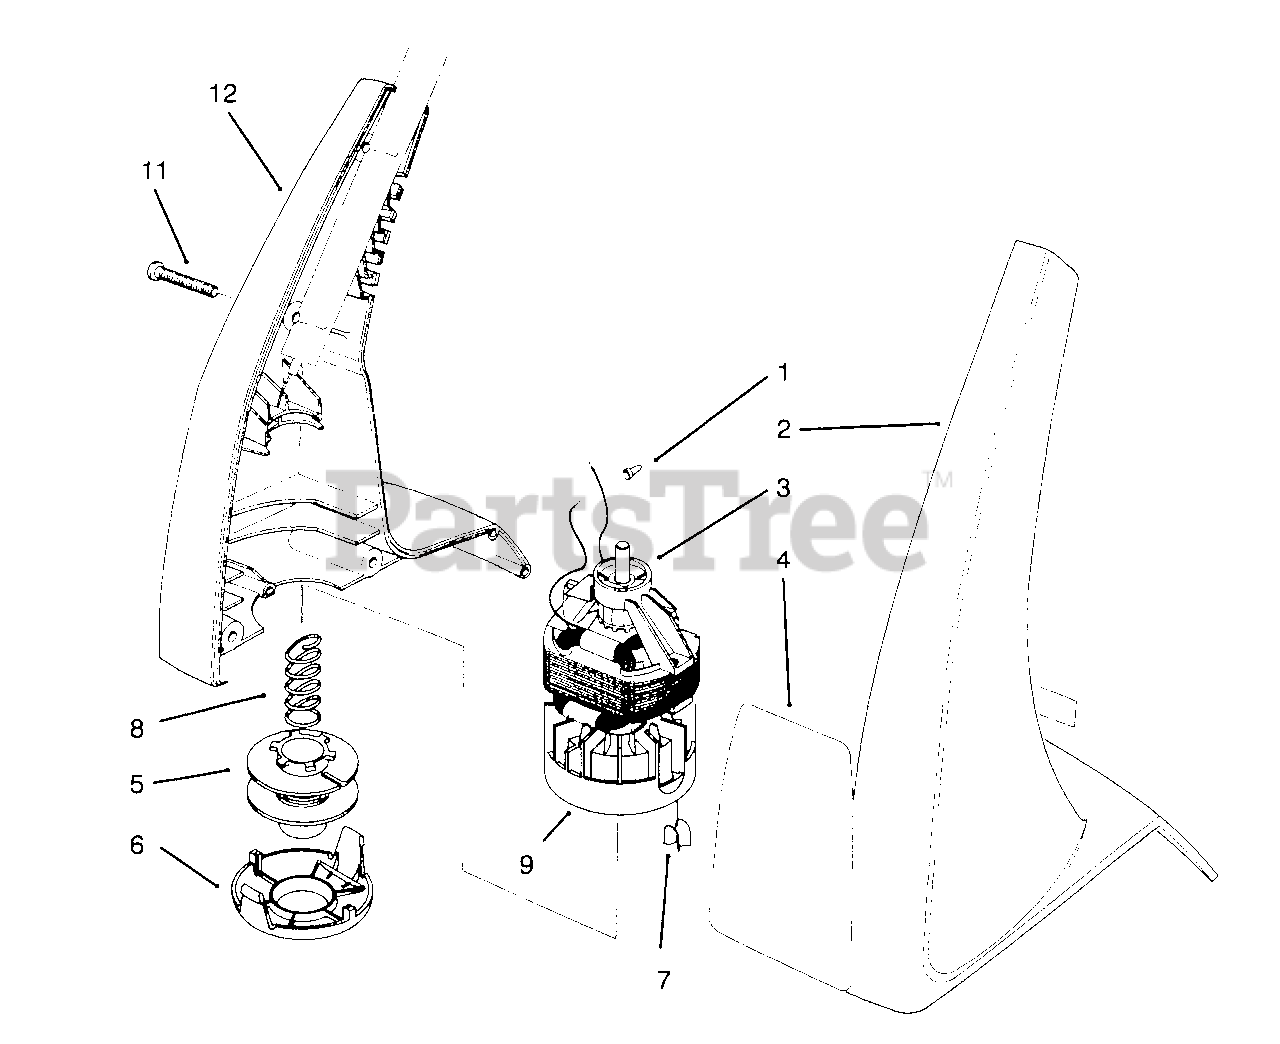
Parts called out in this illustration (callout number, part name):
1	Connector-Wire
2	Housing-L.H.
3	Motor Assembly (Incl. Ref. #9 & 7 )
5	20 Ft. .050 Dia. Cutting Line Prewound on Spool
9	Drum
11	Screw
12	Housing Assembly-R.H.
